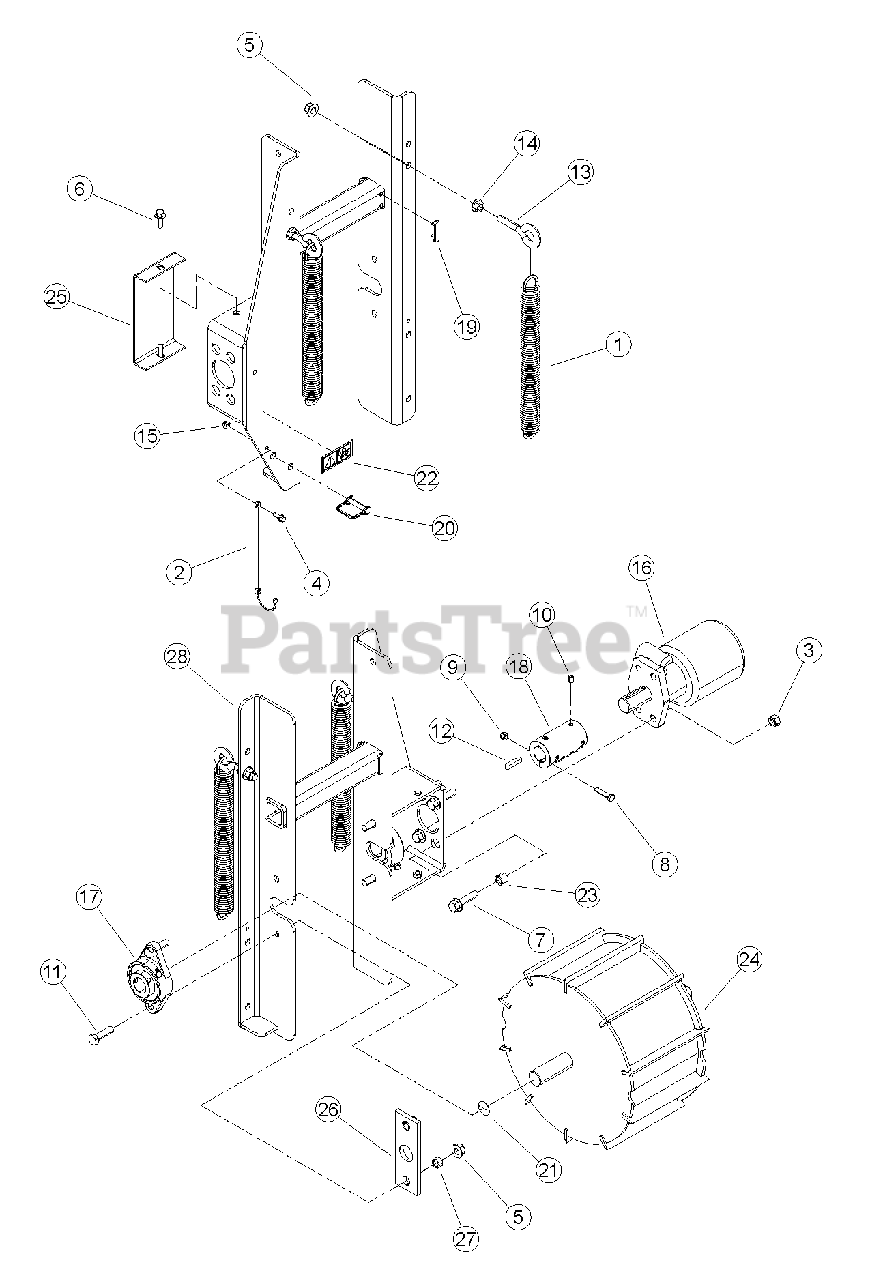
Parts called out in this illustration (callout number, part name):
1	SPRING, EXTENSION
2	LANYARD, NYLON
3	NUT, 1/2" CENTERLOCK GRB ZP
4	BOLT, 1/4-20 X 3/4 HWH GR5 CZP
5	NUT, 1/2-13 NYLOCK FLANGE
6	BOLT, 3/8 X 1 FLANGE NC
7	BOLT, 1/2-13 X 2 HWH GR5 CZP
8	BOLT, 5/16 X 1-1/2 GR5 HEX CPS ZP
9	NUT, 5/16" NE NYLOCK ZP
10	SET SCREW, 3/8 X 1/2 CUP PT SKT
11	BOLT, 1/2 X 1 3/4 GR5 HCPS NC ZP
12	KEY, 5/16 X 1-1/2 SQUARE
13	EYEBOLT, 1/2 X 2" ZP
14	NUT, 1/2 SPIRAL LOCK NC ZP
15	NUT, 1/4-20 NYLOCK-FLANGE
16	MOTOR, 45 CU IN HYDRAULIC
17	BEARING, 1-1/4" DIA 2 BOLT FLANGE
18	COUPLER, 1-1/4 SHAFT
19	WEAR PAD, STD. SPRING HD FRONT
20	PIN, SNAP 3/8 X 1-1/2 USABLE LGH
21	DECAL, ROTATING SHAFT
22	DECAL, CRUSHING ISO
23	SPACER, 0.75 X 0.620
24	WELDMENT, TOP GRAB ROLLER
25	SHIELD, COUPLER
26	BEARING, SLIDE
27	SPACER, .75 OD X .5 ID X .37
28	WELDMENT, ROLLER SLIDE
